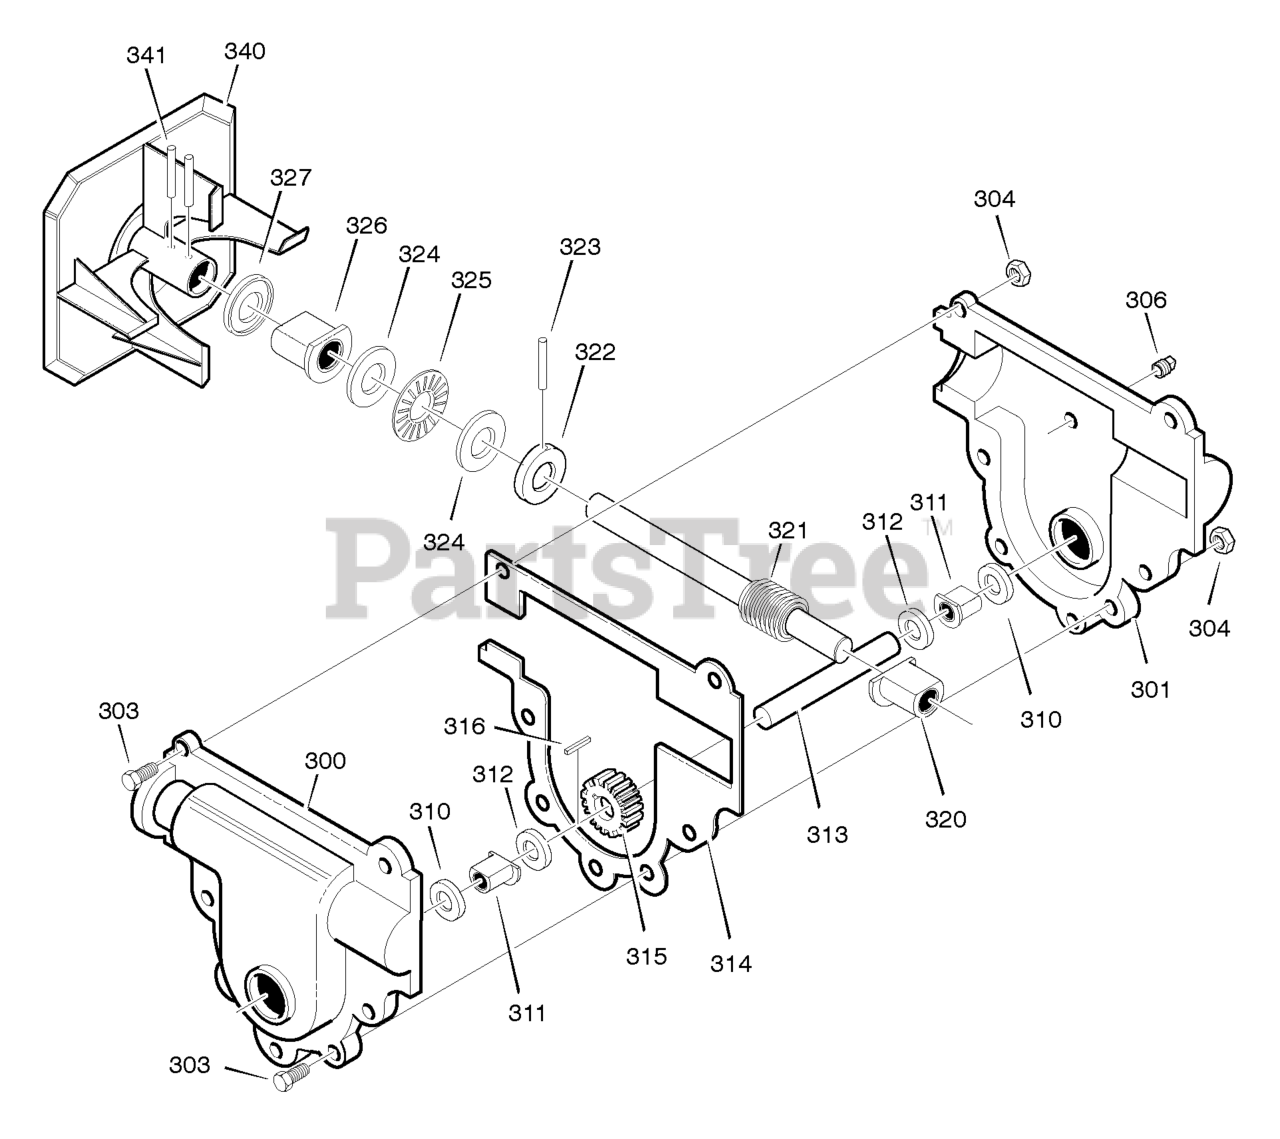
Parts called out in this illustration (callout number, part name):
300	CASE, GEAR, RH
301	CASE, GEAR, LH
303	SCREW,1/4-20X.75
304	NUT,1/4-20
306	SCREW, 3/8-16 x 0.50
310	SEAL, OIL
311	BEARING, FL
312	WASHER, FLAT
313	SHAFT, AUGER OUTPUT
314	GASKET, GEAR BOX
315	GEAR, WORM
316	KEY, WOODRUFF #61
320	BRNG, FL
321	SHAFT, AUGER INPUT (IMPELLER)
322	COLLAR, THRUST
323	PIN, SPRING
324	WASHER, FLAT
325	BRNG, ROLL
326	BRNG, FL
327	SEAL, OIL
340	IMPELLER
341	PIN, SPRING
